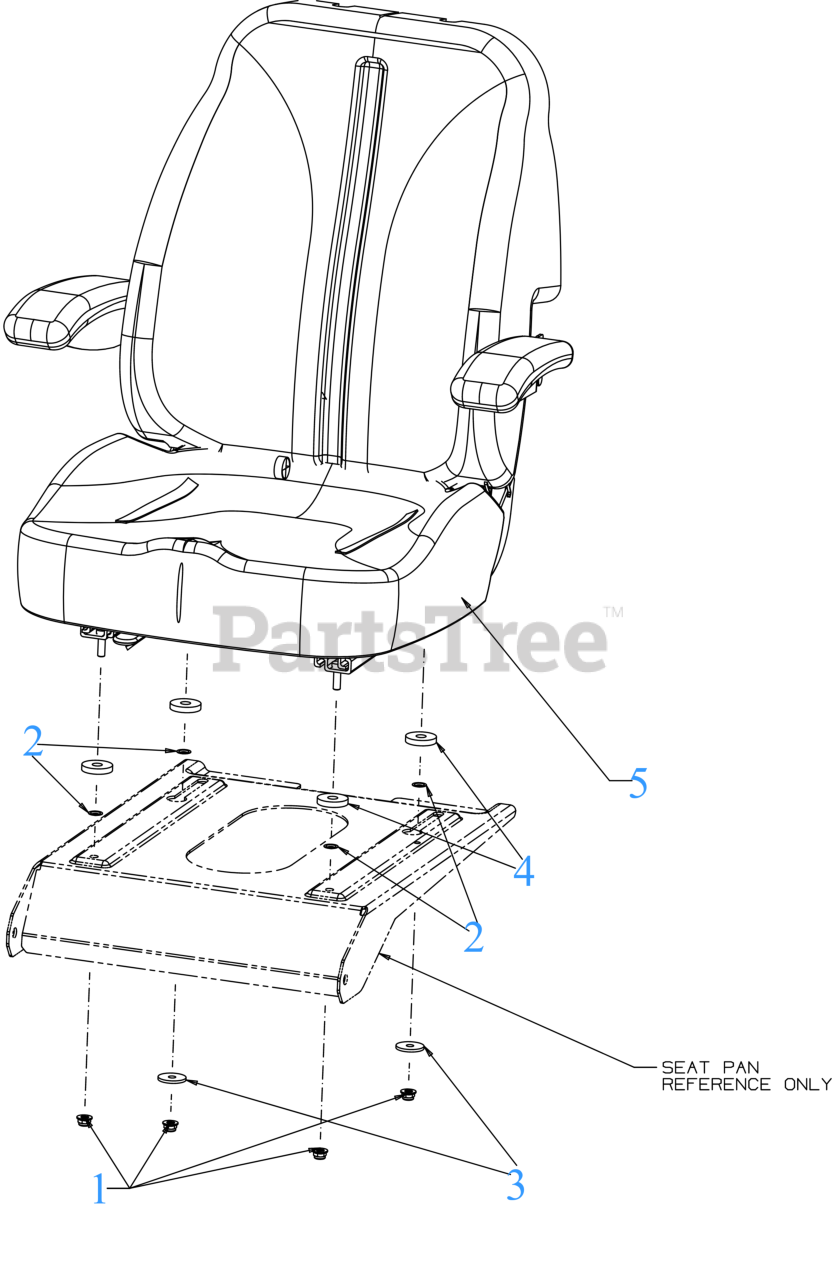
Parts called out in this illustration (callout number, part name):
1	FLANGE LOCK NUT 5/16-18
3	WASHER-5/16 x 1.25X 1.27
4	FLAT WASHER .450X1.375X.250 THK
5	SEAT (CUB/SLIDE/ARM)
